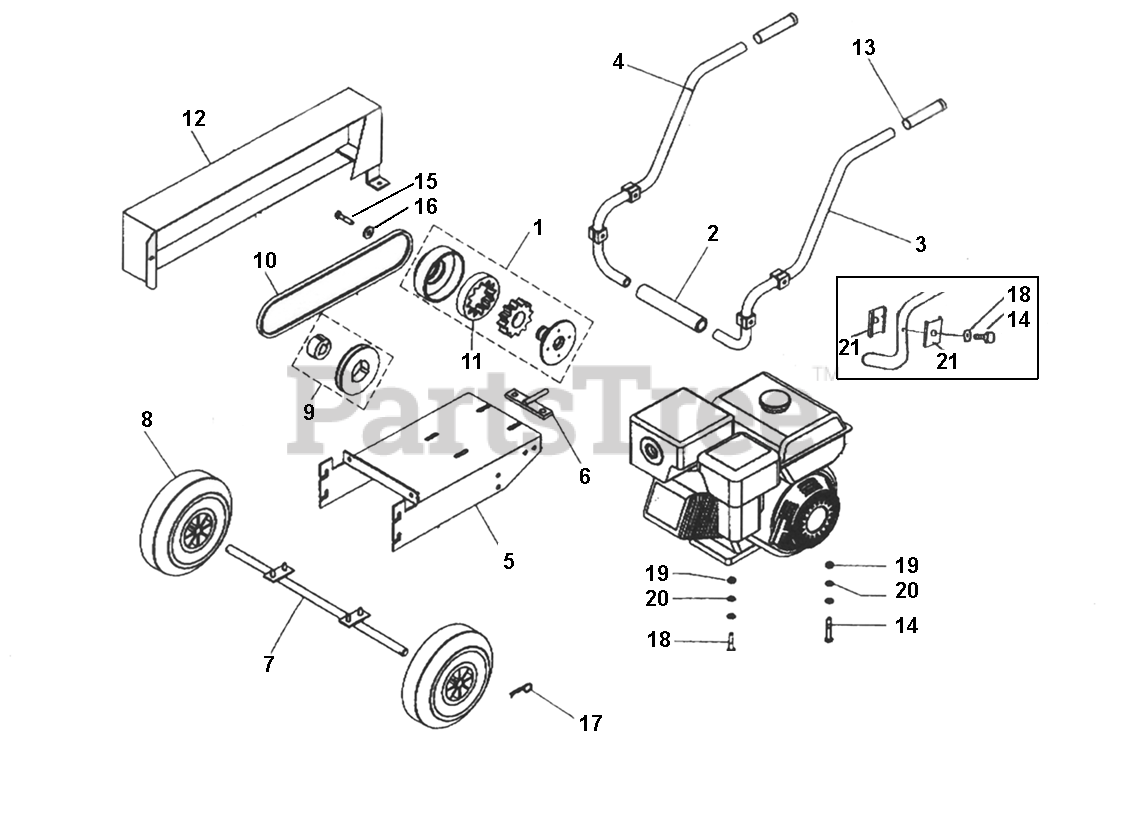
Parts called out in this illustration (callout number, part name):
1	CLUTCH COMPLETE
2	RUBBER HOSE
3	HANDLEBARLH
4	HANDLEBARRH
5	DECK, ENGINE SUPPORT HONDA
6	BELT TENSIONER
7	AXLE, WHEEL
9	PULLEY W TAPER LOCK
10	BELT, HONDA
11	CLUTCH RUBBER, STAR
12	BELT SHIELD HONDA
13	HANDLE GRIP
14	BOLT M10X60 HONDA
15	BOLT 7/16X 1.5" UNF HONDA
18	BOLT M10X50 HONDA
19	BLOCK M10 HONDA
20	WASHER M10 HONDA
